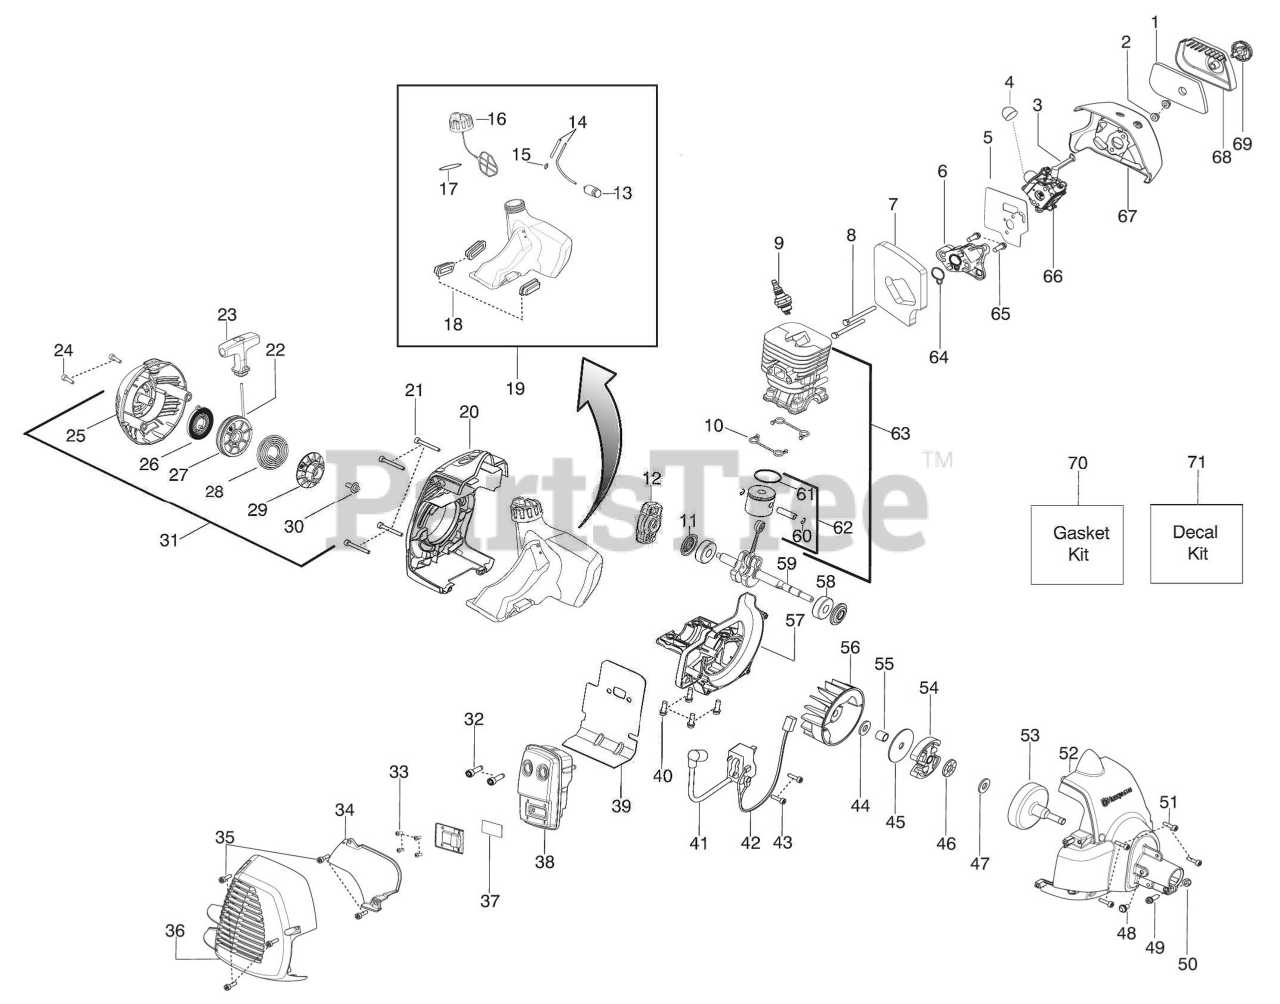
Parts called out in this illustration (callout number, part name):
2	Nut - Carb. Screw
3	Lever - Choke
4	Bulb - Purge
5	Kit - Carb. Gasket
6	Adaptor - Carb.
7	Foam - Gasket
9	Plug - Spark (RCJ-8Y)
10	Seal – Cylinder
11	Seal – Crankshaft
12	Assy - Starter Pawl
13	Assy - Fuel Filter
14	Kit - Fuel Line
15	Fitting - Fuel Line
16	Assy - Cap w/ret.
17	O-Ring - Fuel Cap
18	Isolator - Fuel Tank
19	Kit - Fuel Tank Assy.
20	Shroud - Rear
22	Kit - Rope
23	Handle - Starter
25	Starter Hsg. w/eyelet
26	Kit - Spring
27	Kit - Starter Pulley
28	Spring - Driver
29	Pulley - Driver
31	Assy - Starter Hsg.
32	Bolt - Muffler
33	Screw
34	Shield - Heat
36	Guard - Muffler
37	Kit - Spark
38	Kit - Muffler
39	Gasket - Paper Met.
41	Module - Ignition
42	Assy - Leadwire
45	Washer - Clutch
46	Bearing - Thrust
47	Washer - Thrust
52	Assy - Fan Housing
53	Assy - Clutch Drum
54	Assy - Clutch
57	Crankcase - Cast
59	Assy - Crankshaft
60	Retainer - Piston Pin
61	Ring - Piston
62	Kit - Piston
63	Kit – Cyl./Piston
64	Seal - adaptor
66	Kit – Carb.
67	Airbox
68	Cover - Air Box
69	Assy - Knob
70	Kit - Gasket
71	Kit - Decal
